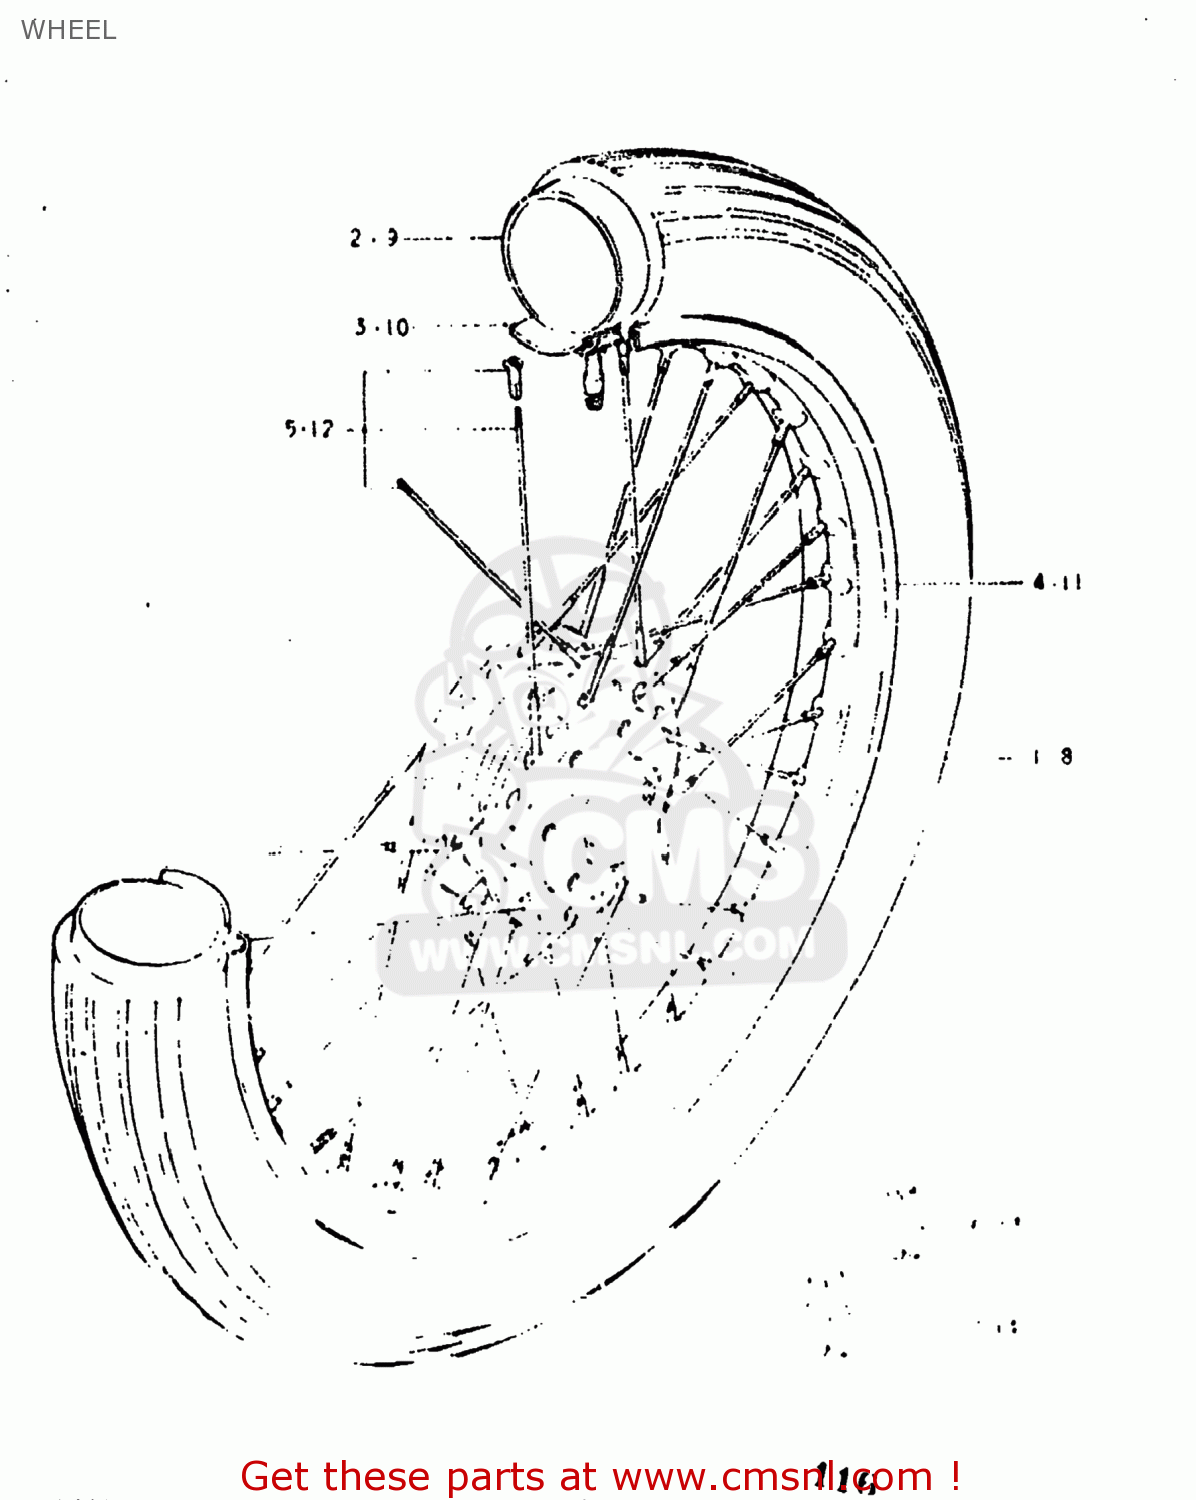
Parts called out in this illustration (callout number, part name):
1	TIRE,FRONT
2	TUBE,INNER
3	PROTECTOR,WHEEL,INNER
4	RIM,FR WHEEL
5	SPOKE SET,FRONT
6	BALANCER,WHEEL (B)
7	BALANCER,WHEEL (30G)
8	TIRE
9	TUBE ASSEMBLY,WHEEL,INNER
10	PROTECTOR,INNER TUBE
11	RIM,RR WHEEL
12	SPOKE SET REAR B,XB
13	BALANCER,WHEEL (B)
14	BALANCER,WHEEL (30G)
